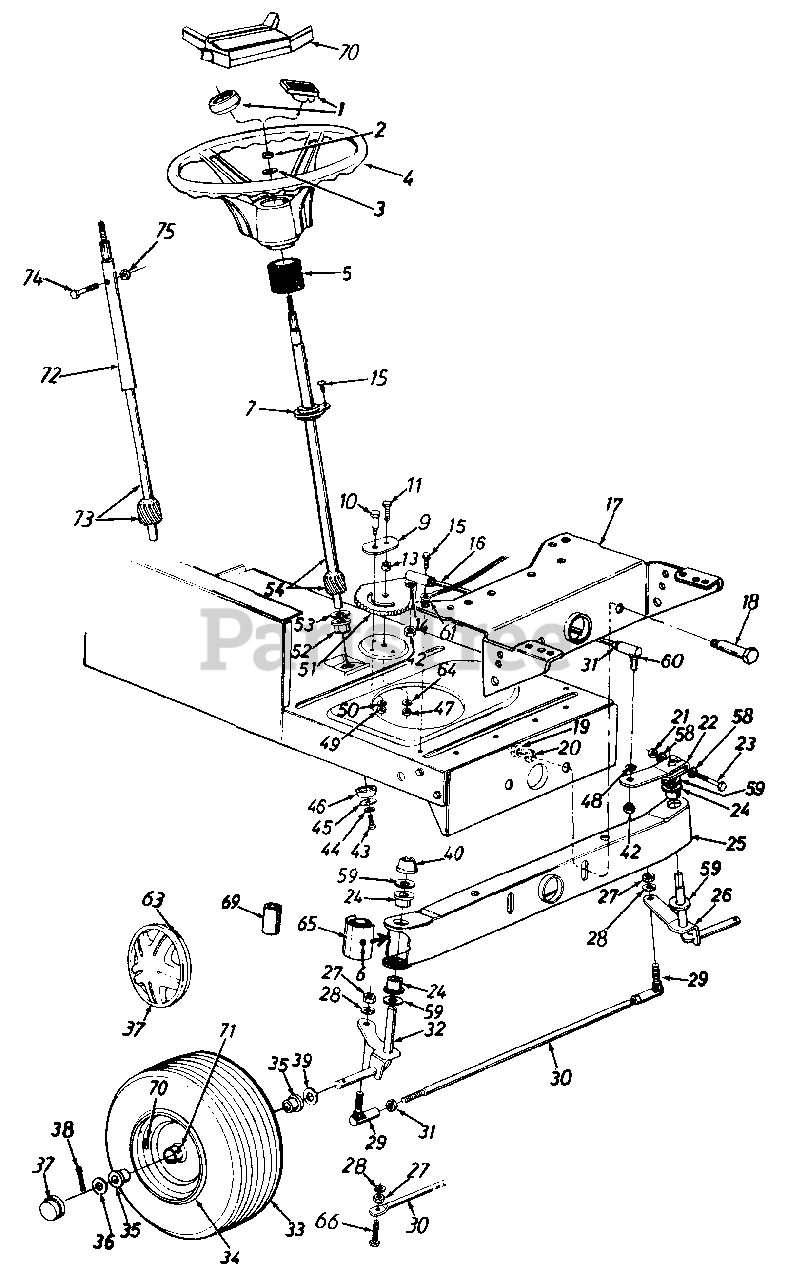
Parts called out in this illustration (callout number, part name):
1	Steering Wheel Cap
2	Hex L-Nut 5/16-24 Thd.
3	Belleville Wash. .345" I.D.
4	Steering Wheel (3 Spoke)
5	Steering Bellow - 4.5"
6	Grease Fitting
7	Flange Bearing .628" I.D. x . 1.36 O.D.
9	Retainer Plate
10	Shoulder Bolt .437" Dia. x .35 Lg. 5/16-18 Thd.
11	Hex Bolt 3/8-24 x 1.0" Lg. (Gr. 5)
13	Spacer .380" I.D. x .625" O.D. x .227
14	L-Wash. 3/8" I.D. (H.D.)
15	Hex Wash. Hd. Self-Tap Scr.
16	Steering Drag Link
18	Shoulder Bolt .498" Dia. x 2.04 Lg. 3/8-16 Thd.
19	Flanged L-Nut 3/8-16 Thd.
20	L-Wash. 3/8" I.D.
21	Hex L-Nut 5/16-24 Thd.
22	Steering Arm Front Axle
23	Hex Bolt 5/16-24 x 2.00" (Gr. 5)
24	Hex Flg. Brg. .632 I.D.
26	Front Axle Ass'y. - L.H.
27	Hex Nut 3/8-24 Thd.
28	L-Wash. 3/8" I.D.
29	Ball Joint 3/8-24 Thd.
30	Tie Rod (Adjustable)
31	Hex Jam Nut 3/8-24 Thd.
32	Front Axle Ass'y. - R.H.
33	Wheel Ass'y. Comp.
36	Fl-Wash. .635 I.D. x 1.59" O.D.
37	Front Wheel Hub Cap
38	Cotter Pin 1/8" Dia. x 1.25"
39	Fl-Wash. .640" I.D. x 1.24" O.D.
40	Push Cap 5/8" Dia. Rod
42	Hex Jam Nut 3/8-24 Thd.
43	Hex L-Bolt 5/16-18 x .62"
44	L-Wash. 5/16" I.D.
45	Fl-Wash. .38" I.D. x 1.25" O.D.
46	Spacer (Plastic)
47	Hex Cent. L-Nut 3/8-24 Thd.
48	L-Wash. 3/8" I.D.
49	Hex Cent. L-Nut 5/16-18 Thd.
50	L-Wash. 5/16" I.D.
51	Steering Gear Segment
52	Hex Flg. Brg. .634 I.D.
53	Fl-Wash. (Hardened)
54	Steering Shaft
58	Wave-Wash. .32" I.D. x .62" O.D.
59	Fl-Wash. (Hardened)
60	Drag Link Ball Joint 3/8-24 Thd.
61	Ext. L-Wash. 5/16" I.D.
63	Spring Clip
64	Bell-Wash. .39" I.D. x 1.38" O.D.
65	Pivot Bar End Cap
66	Hex Bolt 3/8-24 x 1.5" Lg. (Gr. 5)
69	Plastic Tube 1.54" Lg.
70	Steering Wheel Insert
72	Upper Steering Shaft
73	Lower Steering Shaft
74	Hex Bolt 1/4-20 x 1.25" Lg.
75	Hex L-Nut 1/4-20 Thd.
